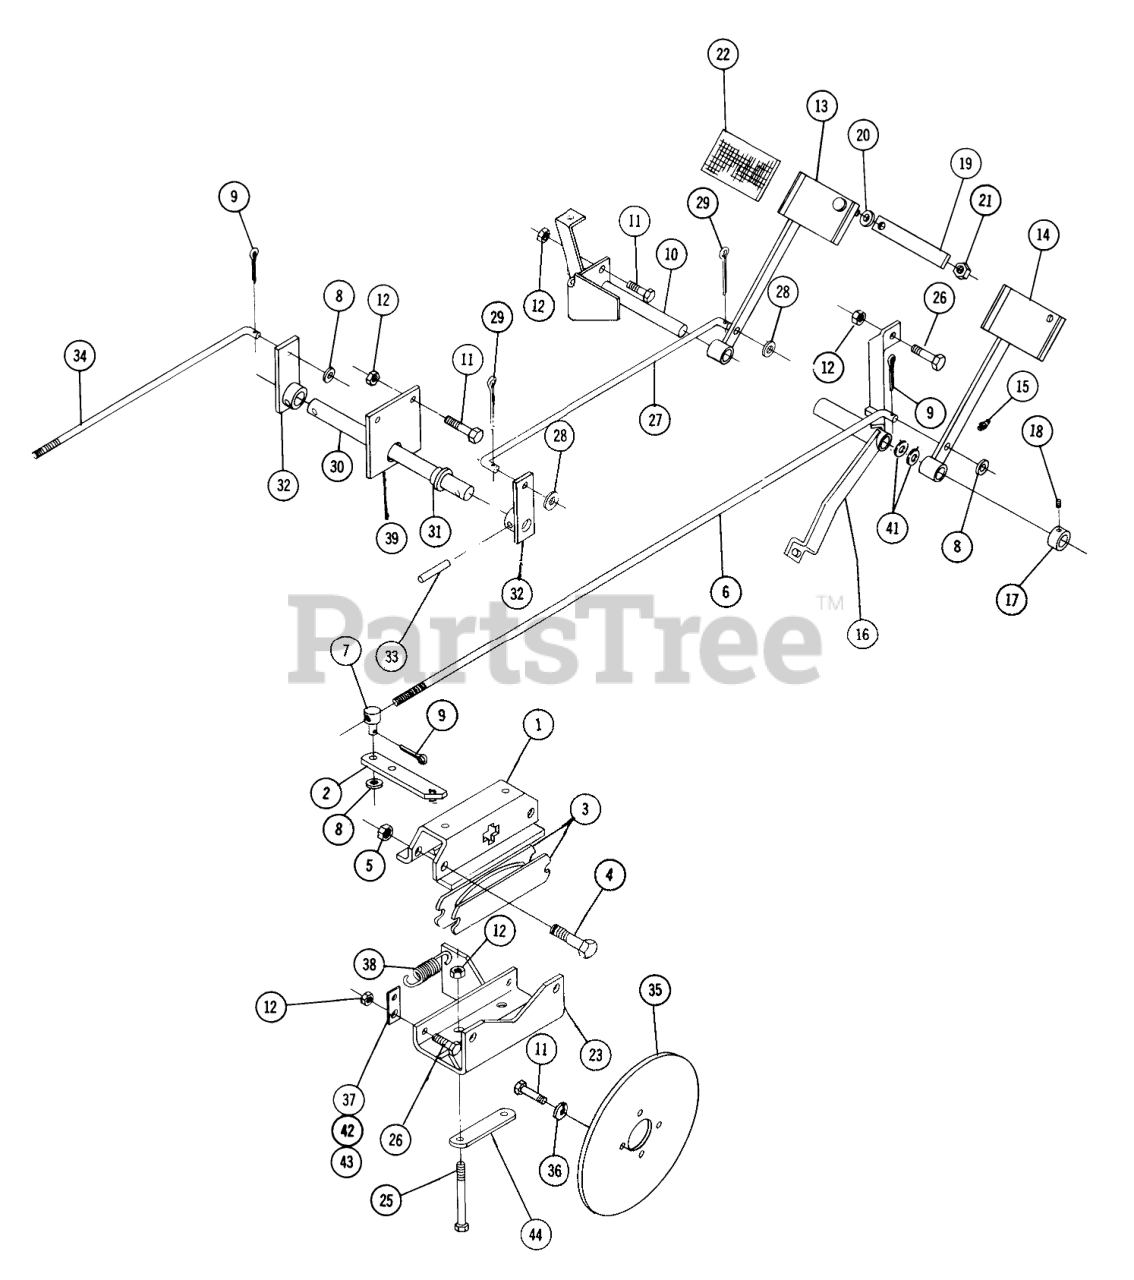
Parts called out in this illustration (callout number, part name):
1	Bracket-Secondary
2	Lever-Assembly
3	PLATE-ASSY- STATOR
4	Guide Sleeve
5	Retaining Ring
6	Rod Assembly
7	Trunnion
8	Washer
9	Hairpin
10	Pedal Pivot Assembly
11	Bolt 3/8-16 x 1
12	3/8-16 E.S.
13	Pedal-L.H.
14	Pedal-R.H.
15	Fitting-Grease
16	Brace Assembly
17	Collar
18	Set Screw-1/4-20 x 1/2
20	Washer
21	3/8-16 E.S.
22	Brake Pedal Pad
23	Plate-Brake Mounting RH
23	Plate-Brake Mounting LH
25	Bolt Hex 3/8-16 x 1
26	Bolt 3/8-16 x 1
27	Rod Assembly
28	Washer
29	Hairpin
30	Shaft
31	BUSHING
32	Arm Assembly
33	SPIROL ROLL PIN
34	Rod Assembly
36	Lockwasher
37	Decal, Caution
38	SPRING
39	Support Bracket
41	Washer
42	PLATE SPRING ANCHOR
43	Spring Tab
44	BRACKET-REAR LINK MOUNTING
